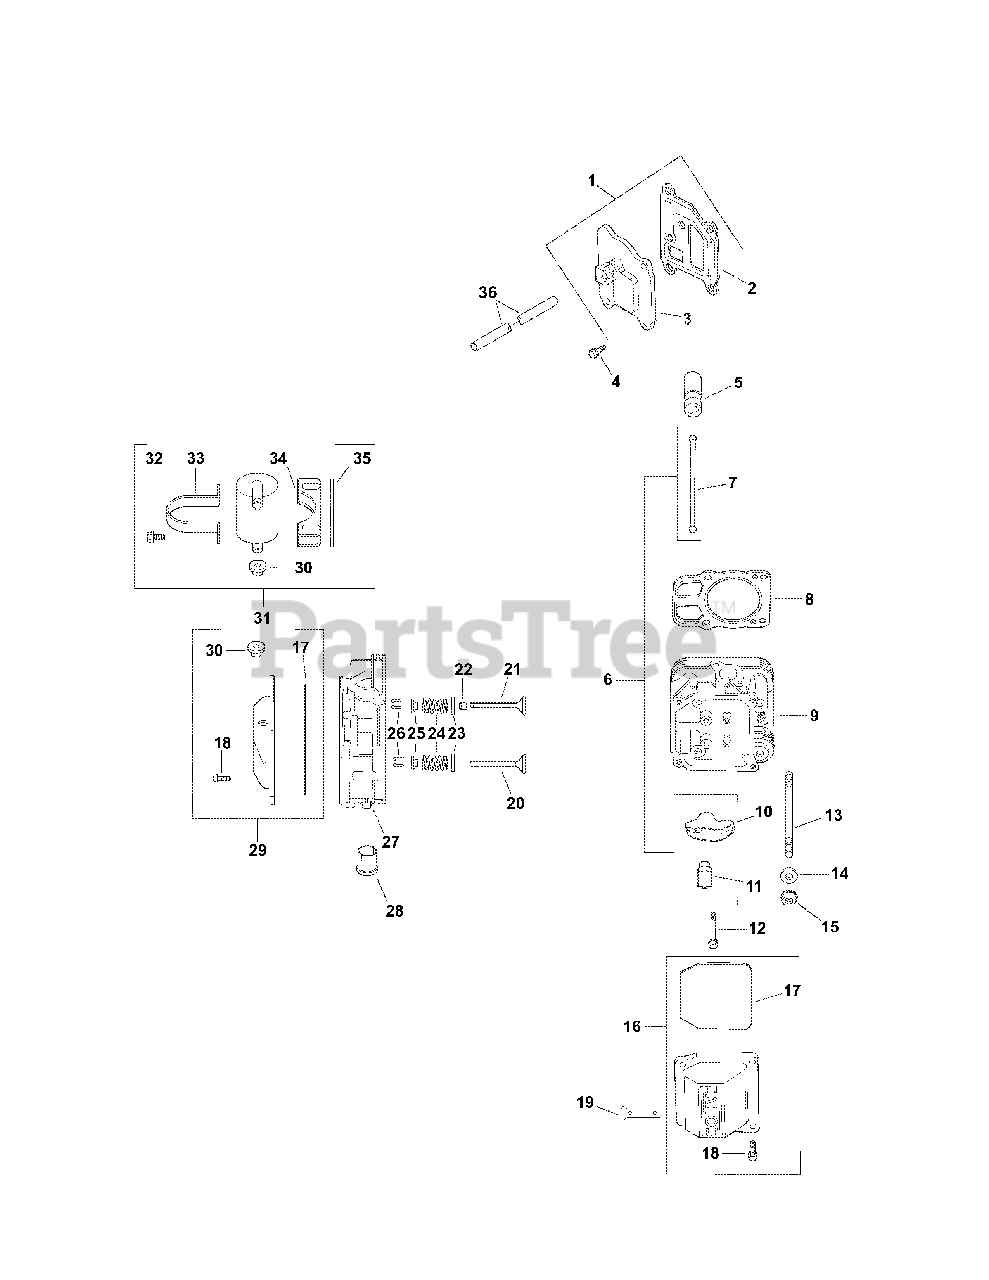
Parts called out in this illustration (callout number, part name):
1	Breather assy, cover w/gasket (Includes 2,3)
2	Gasket, breather
3	Cover, breather
4	Screw, flg thd frm M6x1.0x20
5	Lifter, hydraulic valve
6	Kit, valve train (Includes 7,10,11)
8	Kit, cylinder head gasket (Includes head mtg hdwe)
9	Head assembly, #2 cylinder
11	Pivot, rocker arm
12	Screw, flg M6x1.0x34
13	Stud, M8x1.25, M10x1.5, 105mm
14	Washer, flat 8.6 mm
15	Nut, flg M8x1.25
16	Kit, valve cover-plain (Includes 17,18)
17	O-Ring
18	Screw , flg M6x1.0x30
19	Strap, lifting
20	Valve, exhaust (Std.)
20	Valve, exhaust (.25)
21	Valve, intake (Std.)
21	Valve, intake (.25)
22	Seal, valve stem
23	Retainer, spring
24	Spring, valve
25	Retainer, valve spring
26	Kit, retainer
27	Head assembly, #1 cylinder
28	Liner, exhaust port
29	Kit, rocker cover (separator) (Includes 17,18,30)
30	Grommet, rubber
31	Kit, breather separator (Includes 30,32-35)
32	Screw, flg thd frm M5x0.8x16
33	Strap, breather
34	Bracket, breather separator
36	Hose, breather
